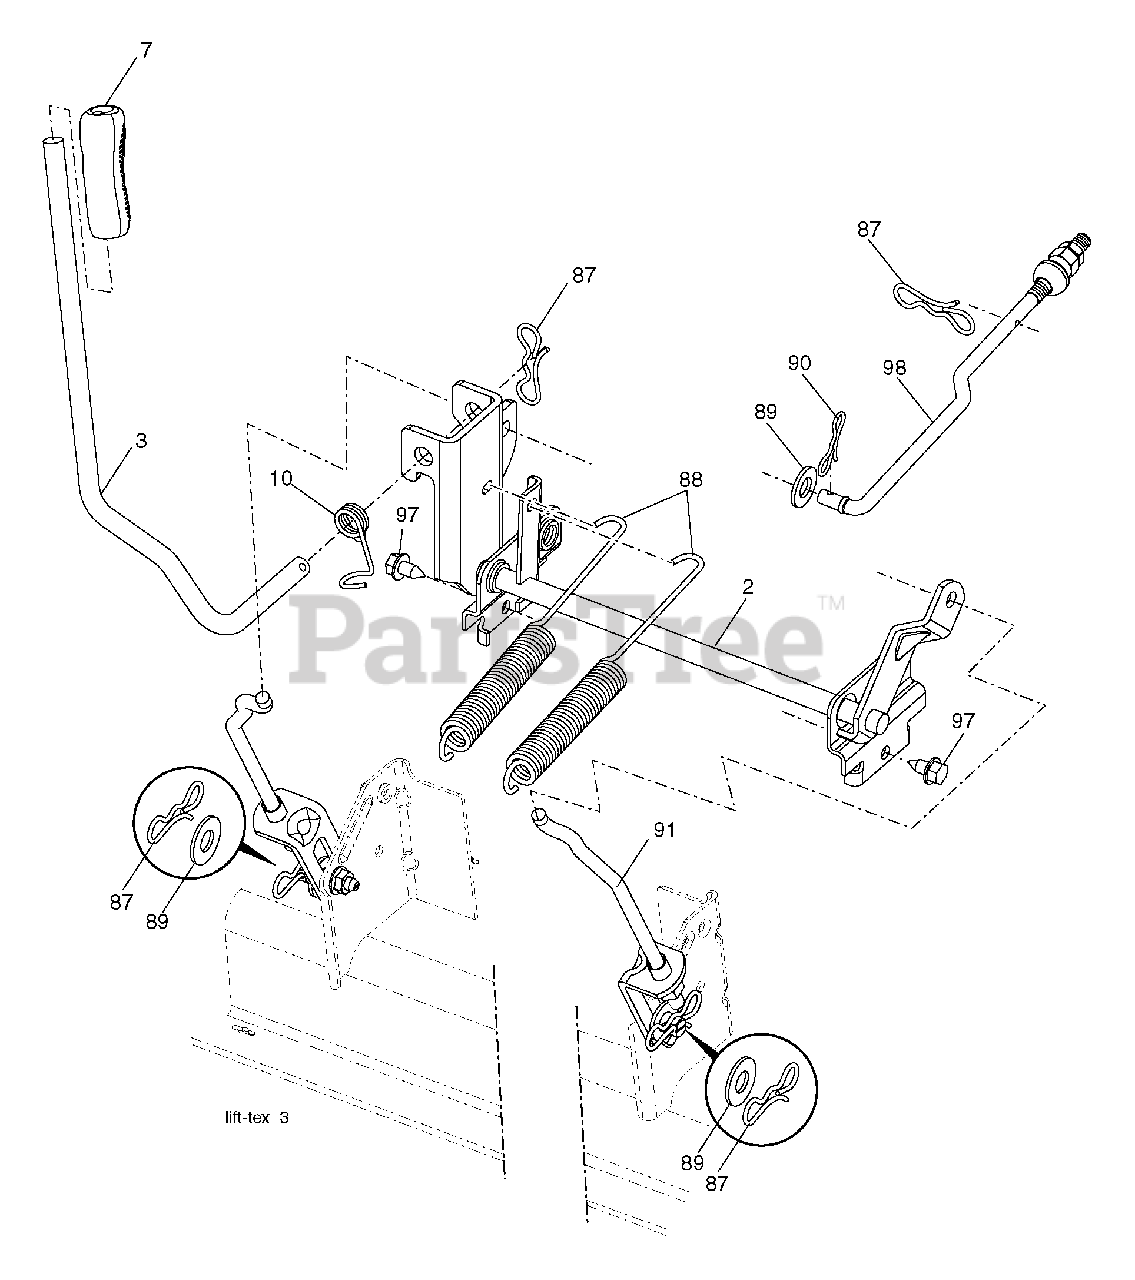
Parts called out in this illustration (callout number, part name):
2	Shaft Asm., Lift
3	Lever Asm., Lift Rh
7	Grip, Lever
10	Spring Torsion
87	Pin Cotter 7/16 Bow Tie Lock
88	Spring Lift Assist
89	Washer Clear Zinc
90	Pin Cotter 5/16 Bow Tie Lock
91	Link Lift Asm. Rear
97	Screw 3/8-16 x .75 Smgml Tap/R.Z
98	Link Asm. Susp. Front
